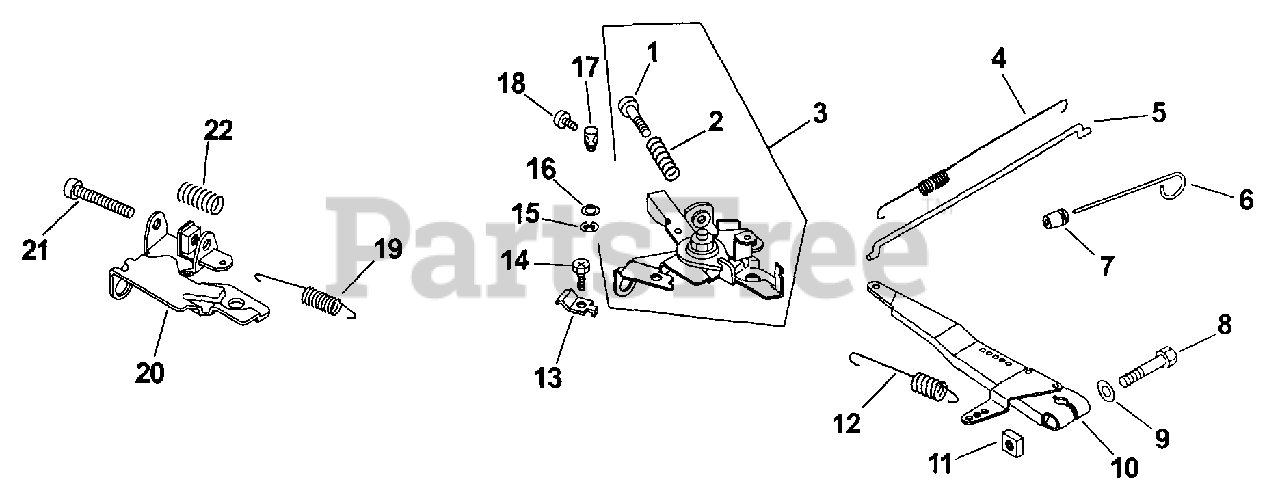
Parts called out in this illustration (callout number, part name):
1	SCREW, PAN HEAD
2	SPRING, COMPRESSION
3	LEVER, THROTTLE
4	SPRING, LINKAGE
5	LINKAGE, THROTTLE
6	LEVER, CHOKE
10	LEVER, GOVERNOR
12	SPRING, GOV
13	BOWDEN CLAMP (#DSC)
14	SCREW, PAN HEAD
